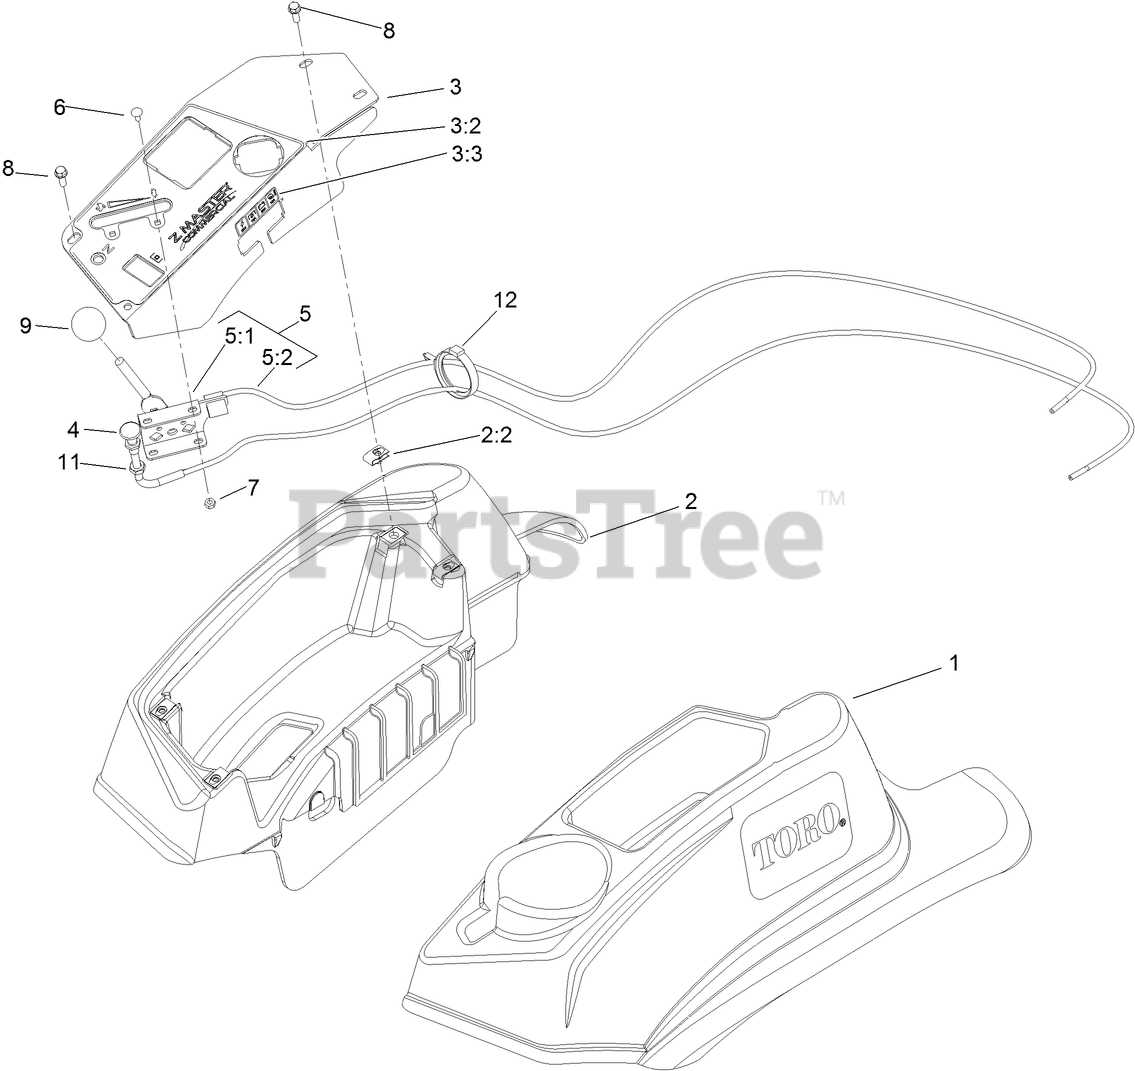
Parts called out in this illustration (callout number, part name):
1	CONSOLE-LH
2	RH CONSOLE ASM
3	CONTROL PANEL ASM
3:2	DECAL-PANEL, CONTROL
3:3	DECAL-FUSES
4	CONTROL-CHOKE
5	THROTTLE CONTROL ASM
5:1	LEVER-THROTTLE
5:2	CABLE-THROTTLE
6	BOLT-CARR
7	NUT-LOCK, NI
8	SCREW-HWH
9	KNOB-BALL
11	NUT-HJ
12	CLAMP-HARNESS
